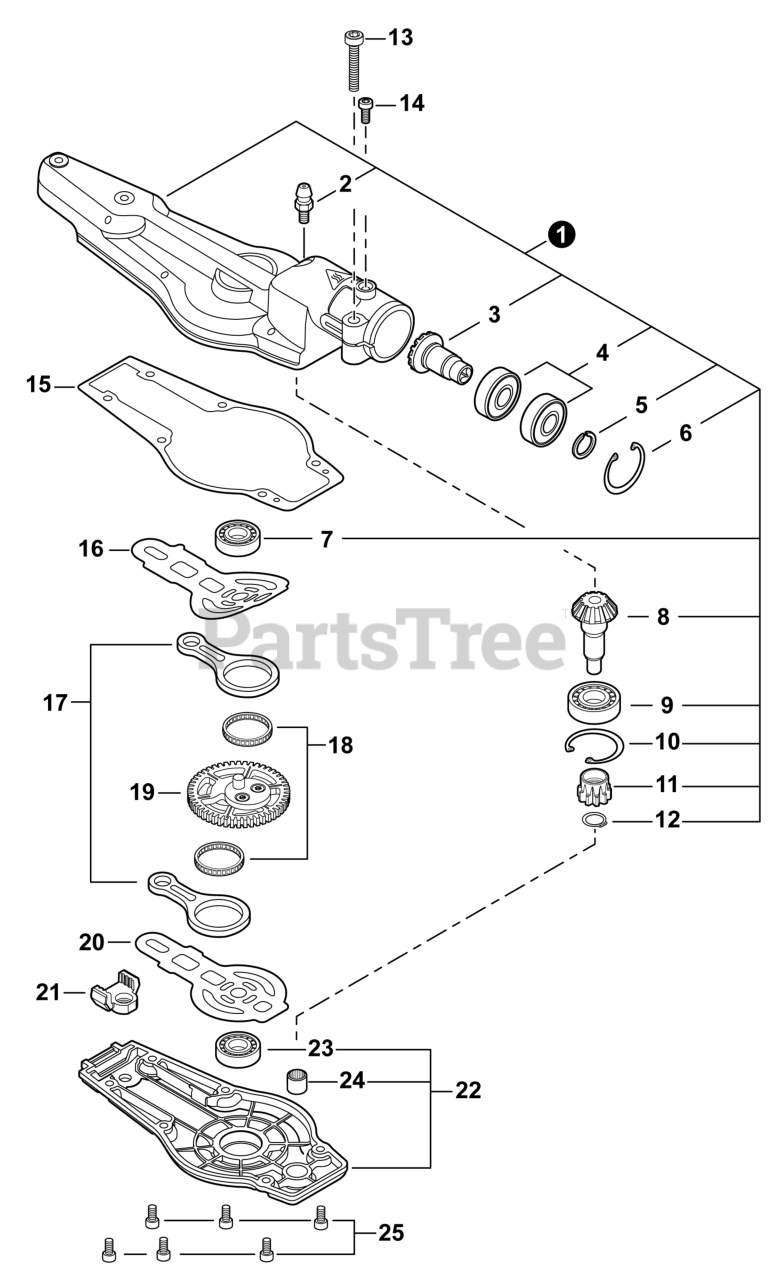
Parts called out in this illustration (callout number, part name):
1	GEAR CASE ASSY
2	FITTING, GREASE
3	GEAR, BEVEL
4	BEARING, BALL 6901
5	RING, SNAP Ø12
6	RING, SNAP 24
7	BEARING, BALL 608
8	GEAR, BEVEL
9	BEARING, BALL 6001
10	RING, SNAP 28
11	GEAR, SPUR
12	RING, RETAINING 8
13	BOLT, TORX 5×25
14	BOLT, TORX 5×10
15	GASKET, GEAR CASE
16	PLATE, WEAR
17	ROD, CONNECTING
18	BEARING, NEEDLE 30
19	GEAR, SPUR
20	PLATE, WEAR
22	COVER ASSY, GEAR CASE
23	BEARING, BALL 608
24	BEARING, NEEDLE
25	BOLT, TORX 4×12
